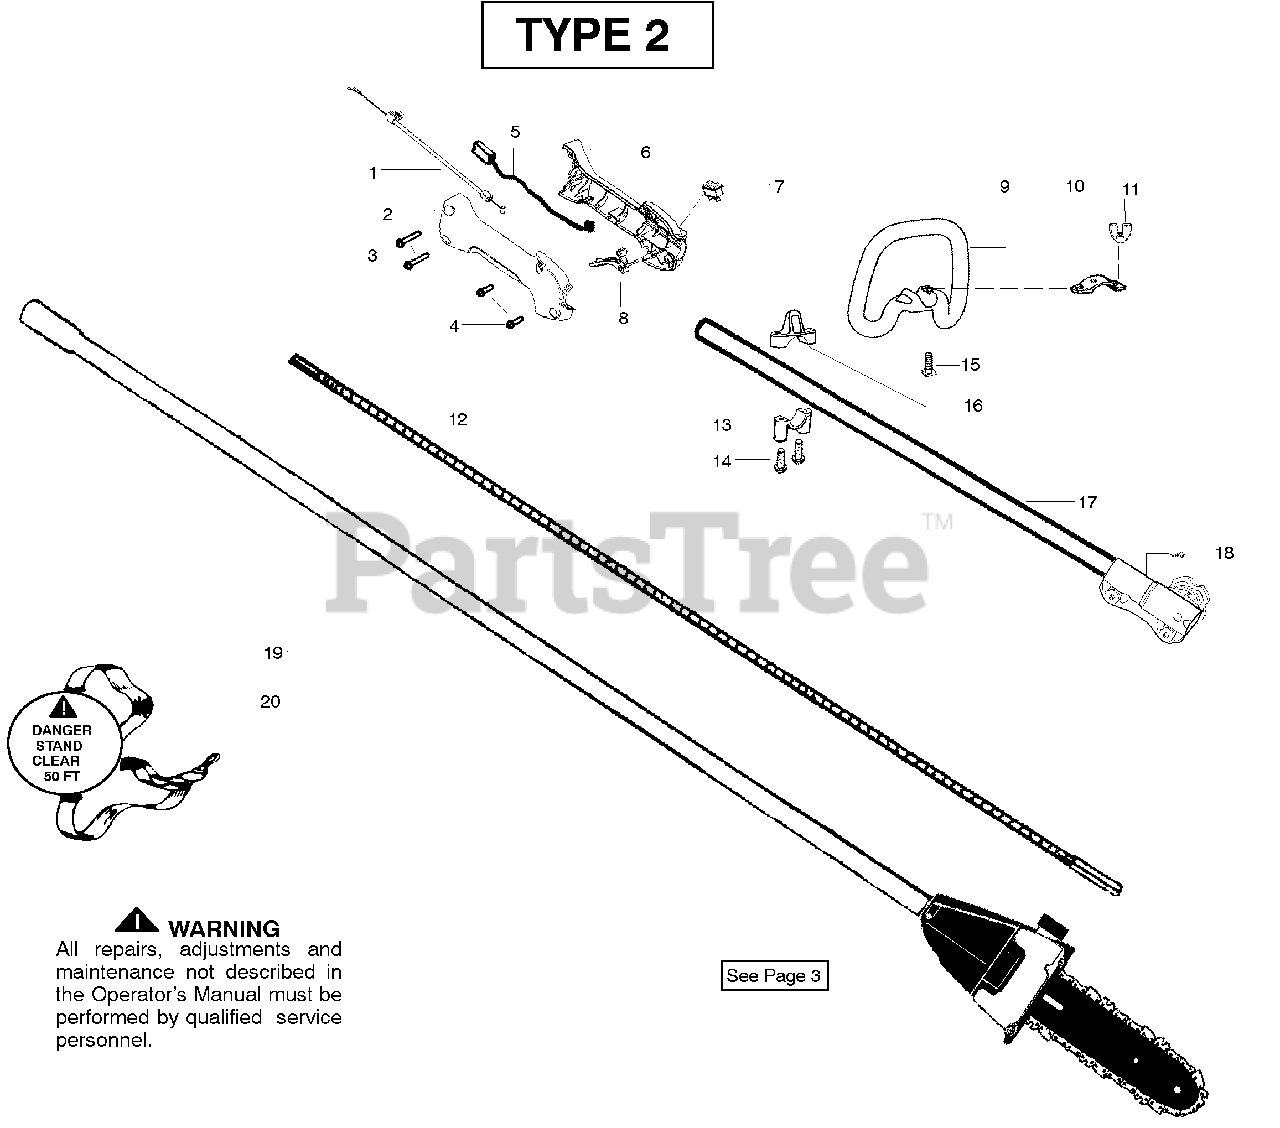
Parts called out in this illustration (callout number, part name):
2	Assy-Throttle Cable
2	Hsg.-Throttle right
6	Hsg. - Throttle left
7	Kit-Switch
8	Trigger
9	Assy-Handle
11	Wingnut
17	Kit-Upper Shaft
19	Assy-Driveshaft
20	Assy-Shoulder Strap
